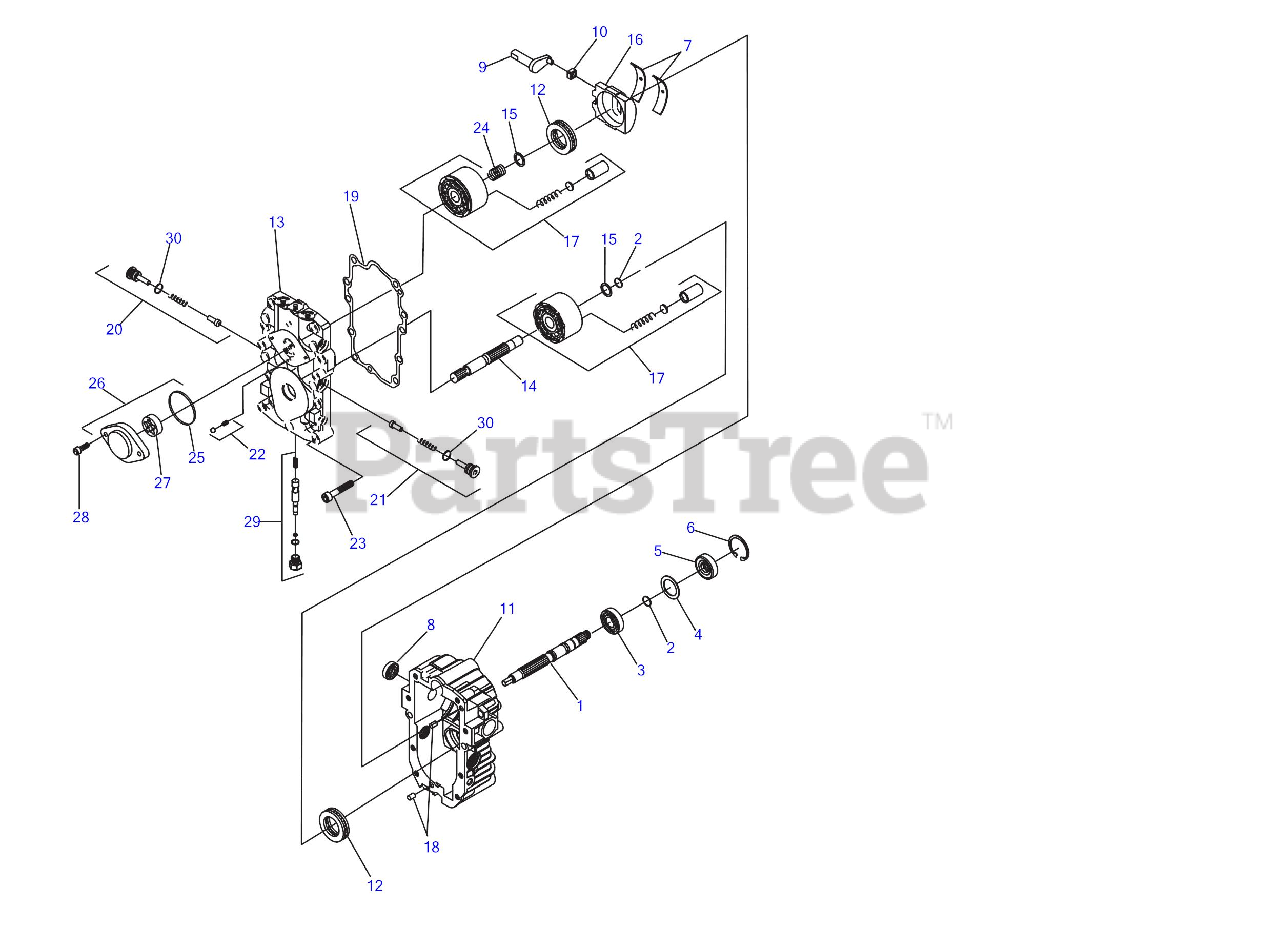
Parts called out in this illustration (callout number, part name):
1	Shaft, Pump (Splined)
2	Ring, Retaining
3	Bearing, Ball
6	Ring, Retaining
7	Bearing, Cradle
9	Arm, Trunnion
10	Guide, Slot
11	Housing Kit
12	Bearing Assembly, Thrust Ball
13	Center Section Kit
14	Shaft, Motor
15	Washer, Block Thrust
16	Swash Plate
17	Block Assembly
19	Gasket, Center Section
20	Kit, Check Valve
21	Kit, Orificed Check Valve
22	Kit, Charge Relief Valve
23	Screw, Socket Hd
24	Spring, Block
26	Kit, Charge Pump
27	Gerotor Assy
28	Screw, Socket Hd
29	Bypass Valve Kit
